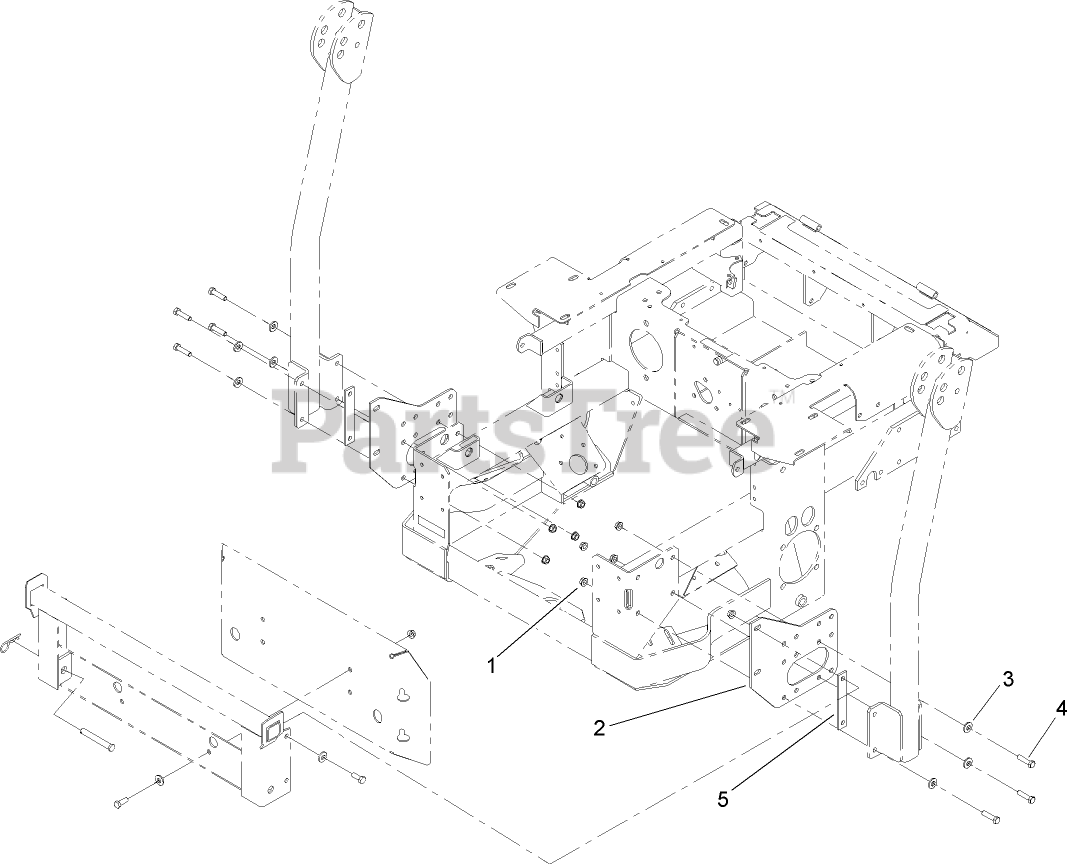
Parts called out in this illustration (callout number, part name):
1	NUT-HHF, WHIZ
2	PLATE-MOUNT, BAGGER
3	WASHER-BELLEVILLE
4	SCREW-HH
